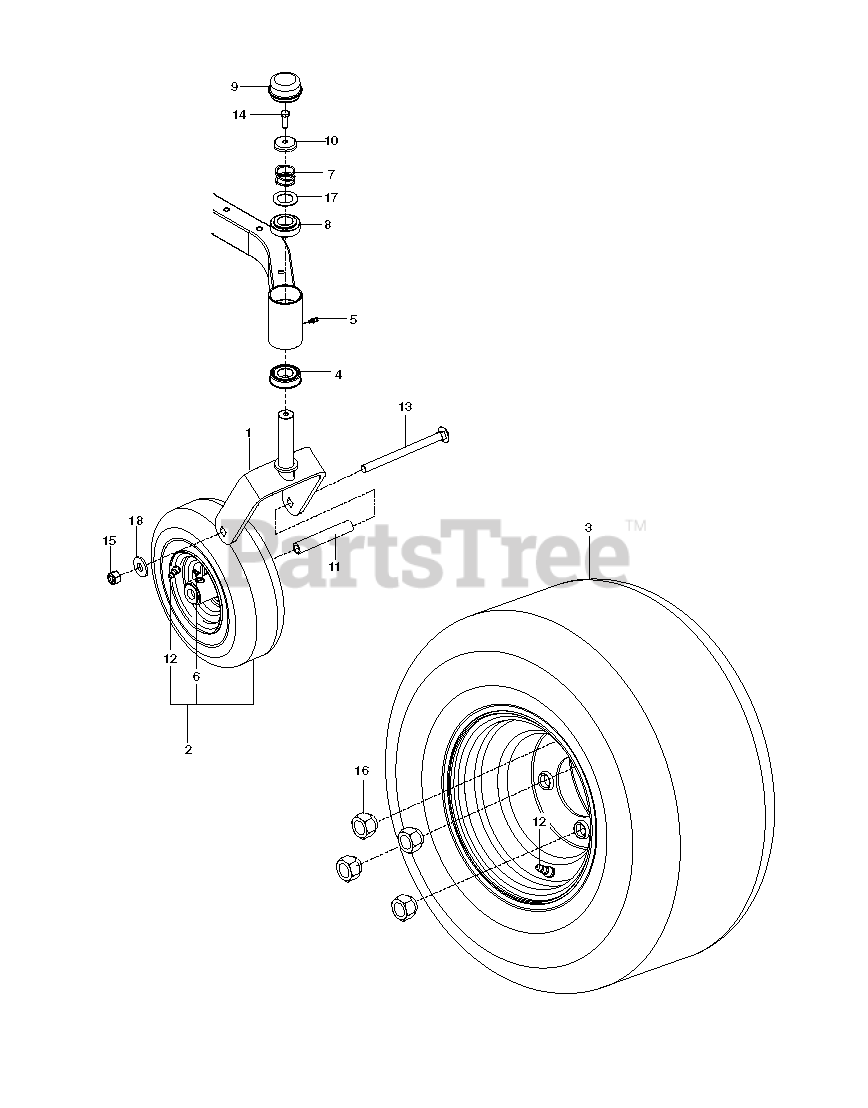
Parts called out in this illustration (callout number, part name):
1	YOKE.CASTER.ORANGE
2	WHEEL ASSY, WIDE, RZ
3	WHEEL.A500.18 X 9.5-8.SILVER
4	BEARING FLANGED
5	ZERK, 3/16, DRIVE IN
6	ZERK
7	SPRING, CASTER
8	BUSHING, CASTER
9	GREASE CAP
10	CASTER.PLUG
11	SPACER, PIVOT
12	VALVE STEM TR-412
13	RHSNB 1/2-13 X 7.5
14	5/16-18X1 HHB G5W/NY
15	NUT 1/2-13 HEX CNTRLK GR 5 ZD
16	LUG NUT 1/2F
17	WASHER, 1.025 ID X 1.64
18	WASH USS FLAT 1/2
